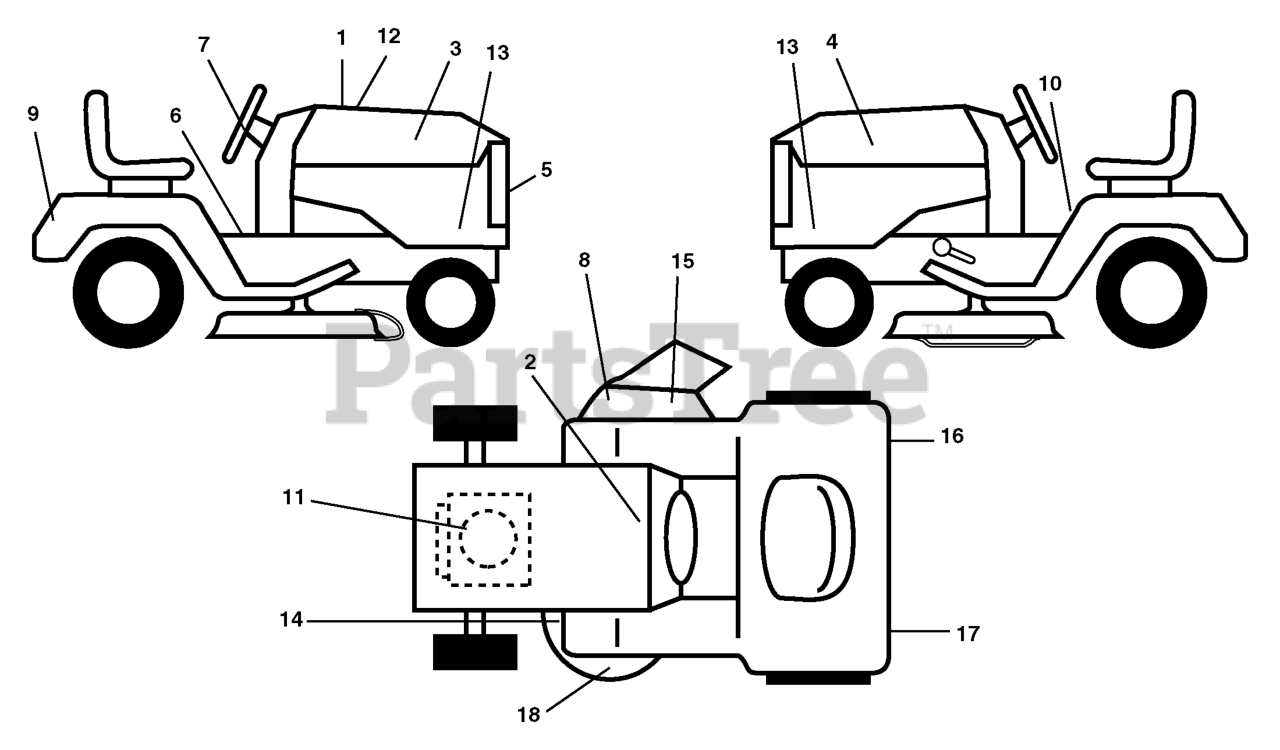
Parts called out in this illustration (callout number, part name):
1	DECAL HOOD CUST. RESP.
2	DECAL BTRY SYMBOLS
3	DECAL HOOD RH
4	DECAL HOOD LH
5	DECAL.GRILLE.HUSQ
7	DECAL.WHEEL.STEERING.HUSQ.PERM
8	DECAL.WARN.KEEP.HAND.AWAY
9	DECAL, FENDER
10	DECAL FENDER DANGER
11	Decal Engine
12	HOOD DECAL
13	DECAL HOOD SIDES
14	DECAL V BELT SCHEMATIC
15	DECAL DECK "B" 42"
16	DECAL RH REFLECTOR
17	DECAL REFLECTOR LH
